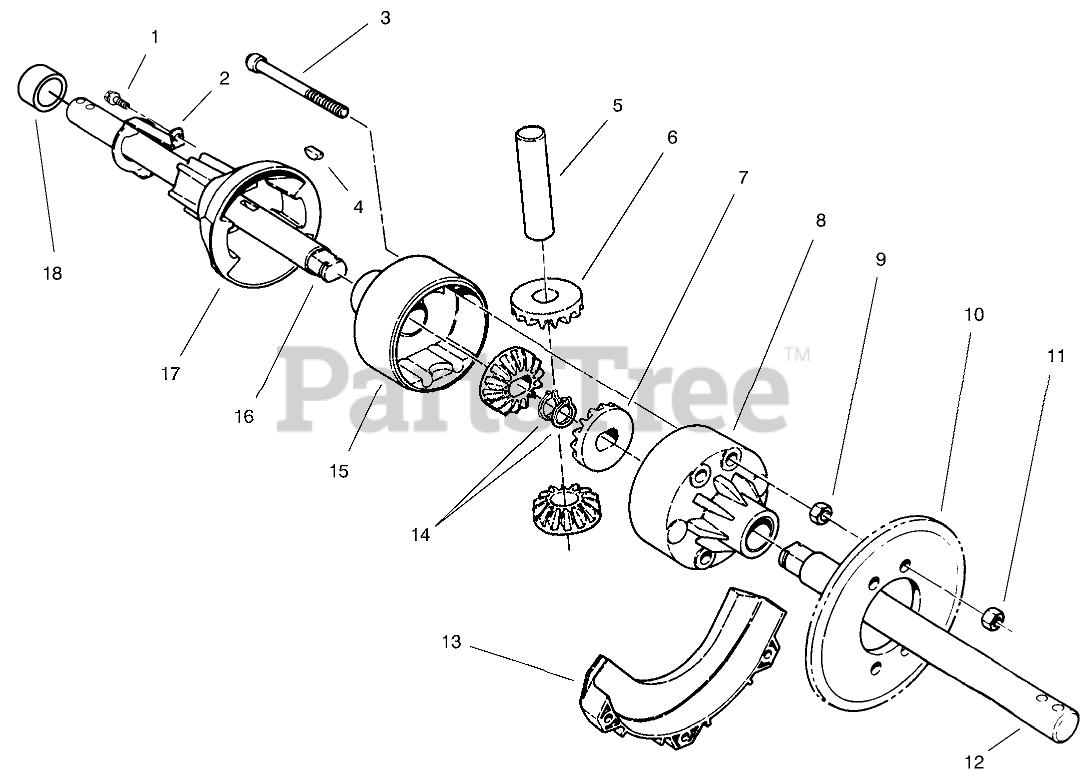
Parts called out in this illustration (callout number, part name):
1	SCREW-HWH
2	SPRING-LOCKOUT
3	SCREW-HSBH
4	KEY-WOODRUFF
5	Shaft-Cross
6	Gear-Cross Shaft Pinion
7	Gear-Side Pinion
8	HOUSING ASSY - FEMALE
9	NUT-HEX
10	SPROCKET-27T
11	NUT-LOCK, NI
12	SHAFT - DIFFERENTIAL,LH
13	GUARD-CHAIN
14	RING-RETAINING
15	HOUSING ASSY - MALE
16	SHAFT - DIFFERENTIAL,RH
17	COUPLING-DIFFERENTIAL
18	SPACER
